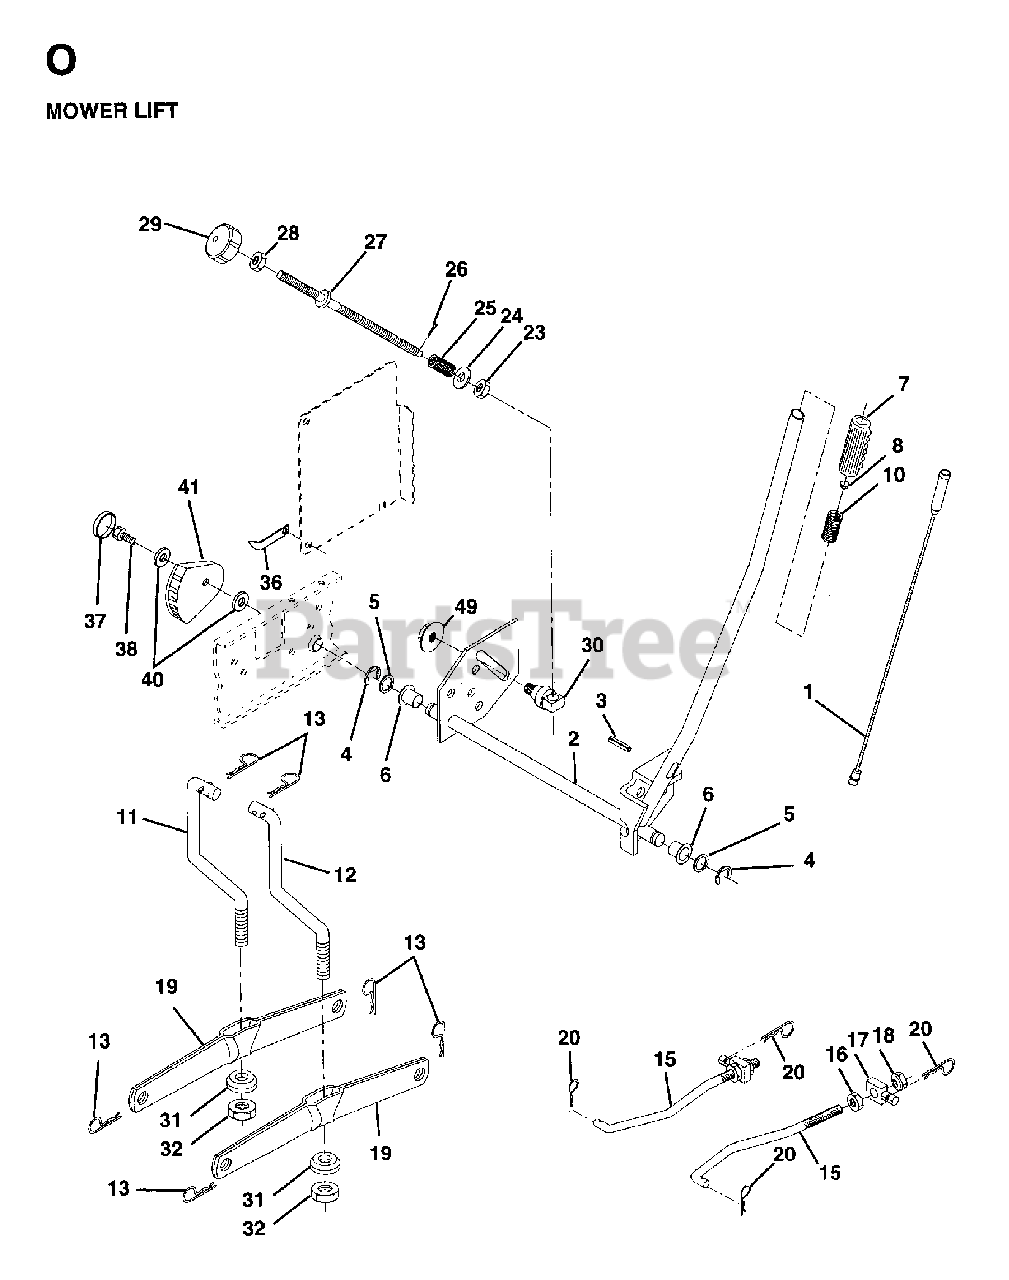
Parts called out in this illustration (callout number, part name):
1	WIRE, INNER HANDLE
2	SHAFT ARM LIFT RH
3	PIN GROOVE
4	RETAINING RING LT
6	BEARING.NYLON
7	GRIP
8	PLUNGER BUT KIT
10	SPRING, COMP T
11	LINK LIFT LH
12	LINK LIFT RH
13	RETAINER-SPRNG RB
15	FRONT LINK
16	NUT
17	TRUNION
18	NUT
19	ARM.REAR.SUSPENSION
20	SPRING RETAINER
25	SPRING**
26	COTTER PIN
27	ROD ADJ LIFT
28	NUT
29	KNOB INF 3/8-16
31	BEARING PIVOT
32	NUT CROWNLOCK 3/8-24
36	POINTER, HEIGHT INDICATOR
37	PLUG,HOLE
38	SCREW
41	IND. HEIGHT STLT
49	NUT
